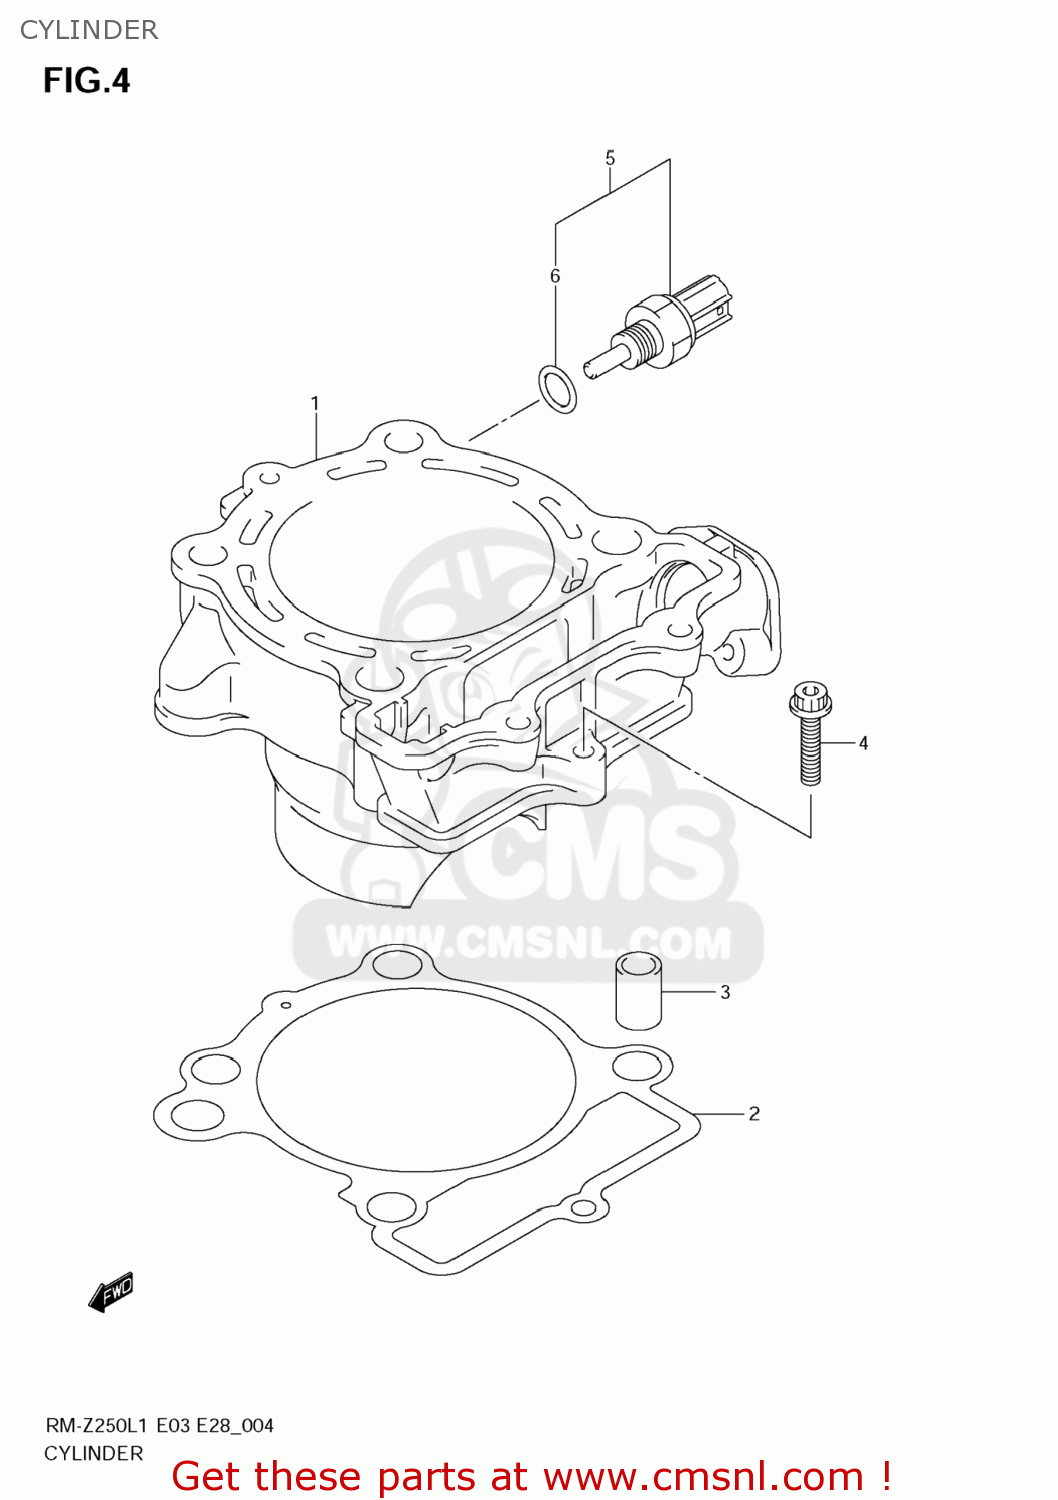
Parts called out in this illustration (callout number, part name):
1	CYLINDER
2	GASKET,CYLINDER (NAS)
3	PIN
4	BOLT
5	SENSOR,WATER TEMP
6	O RING
